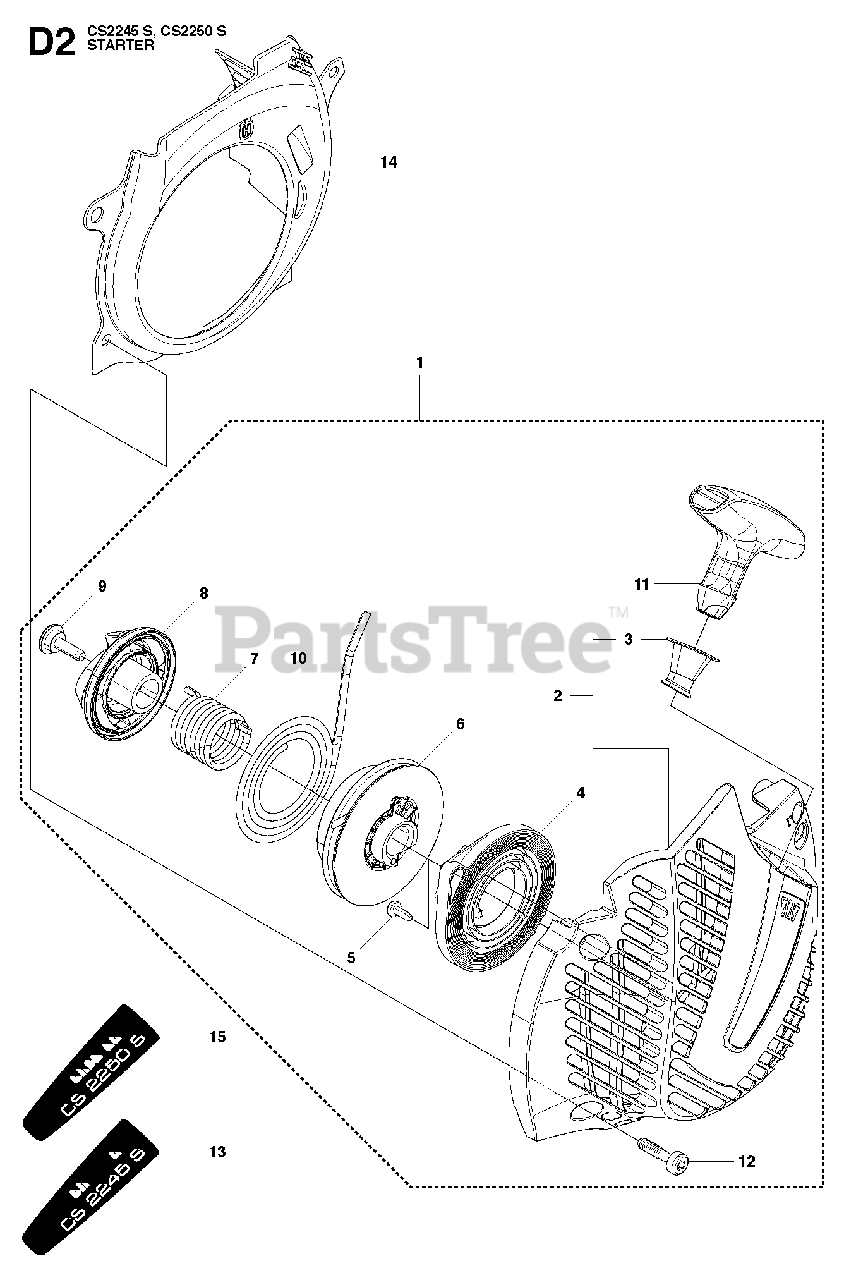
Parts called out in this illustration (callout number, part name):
1	STARTER ASSY
3	SLEEVE
4	SPRING CASSETTE ASSY
5	SCREW
6	STARTER PULLEY
7	SPRING
8	CARRIER
9	SCREW
10	STARTER ROPE
11	STARTER HANDLE
12	SCREW
14	COOLING AIR CONDUCTOR
15	LABEL
